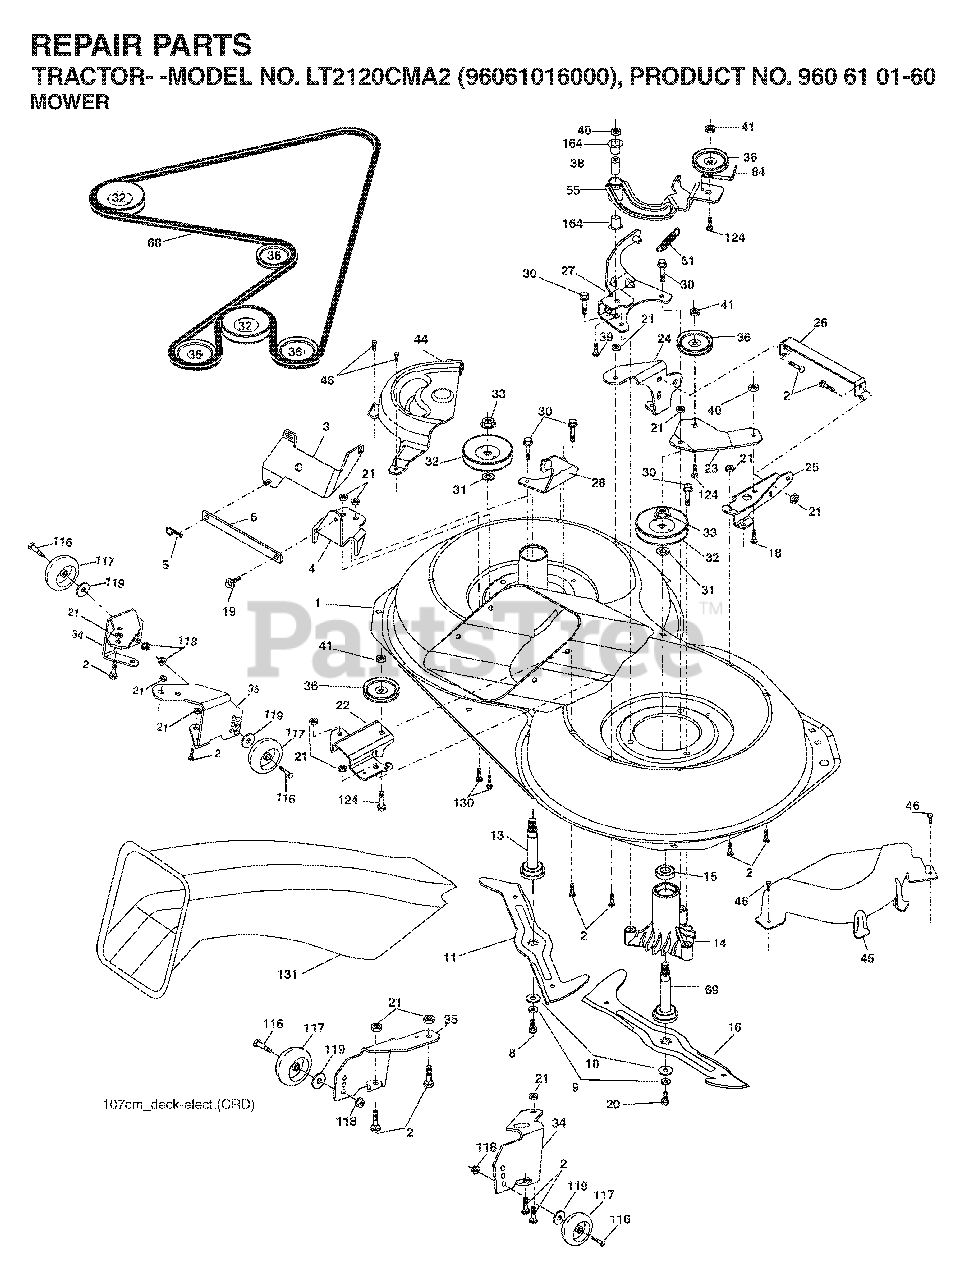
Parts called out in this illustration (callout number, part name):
2	BOLT
3	BRACKET
5	RETAINER-SPRNG RB
6	BAR SWAY
9	LOCKWASHER
10	WASHER.BLADE
11	BLADE.3N1.LH.CRD
13	SHAFT ASM VENT
14	HSG MANDREL
16	BLADE.3N1.RH.CRD
18	BOLT
19	BOLT SHD 5/16-18
21	LOCKNUT
22	BRACKET
23	BRACKET
27	BRACKET
30	SCREW, WASHER HEAD
31	WASHER.SPACER.MANDREL
33	NUT.FLANGE.LOCK.TOP
36	PULLEY.IDLER.4.25
40	LOCKNUT
41	NUT LOCK FLG 3/8-16 UNC
45	MANDREL COVER
46	SCREW.1/4-20X5/8
55	ARM IDLER
68	HEX-BELT 107 MOWER
69	SHAFT.ASM.W/LWR.BRG.RH.THREAD
84	KEEPER, BELT IDLER
116	SHOULDER BOLT
117	WHEEL. GUAGE RALLY
118	LOCKNUT
119	WASHER
124	BOLT.3/8-16X1.50
131	CHUTE BAGGER
164	BRNG T
